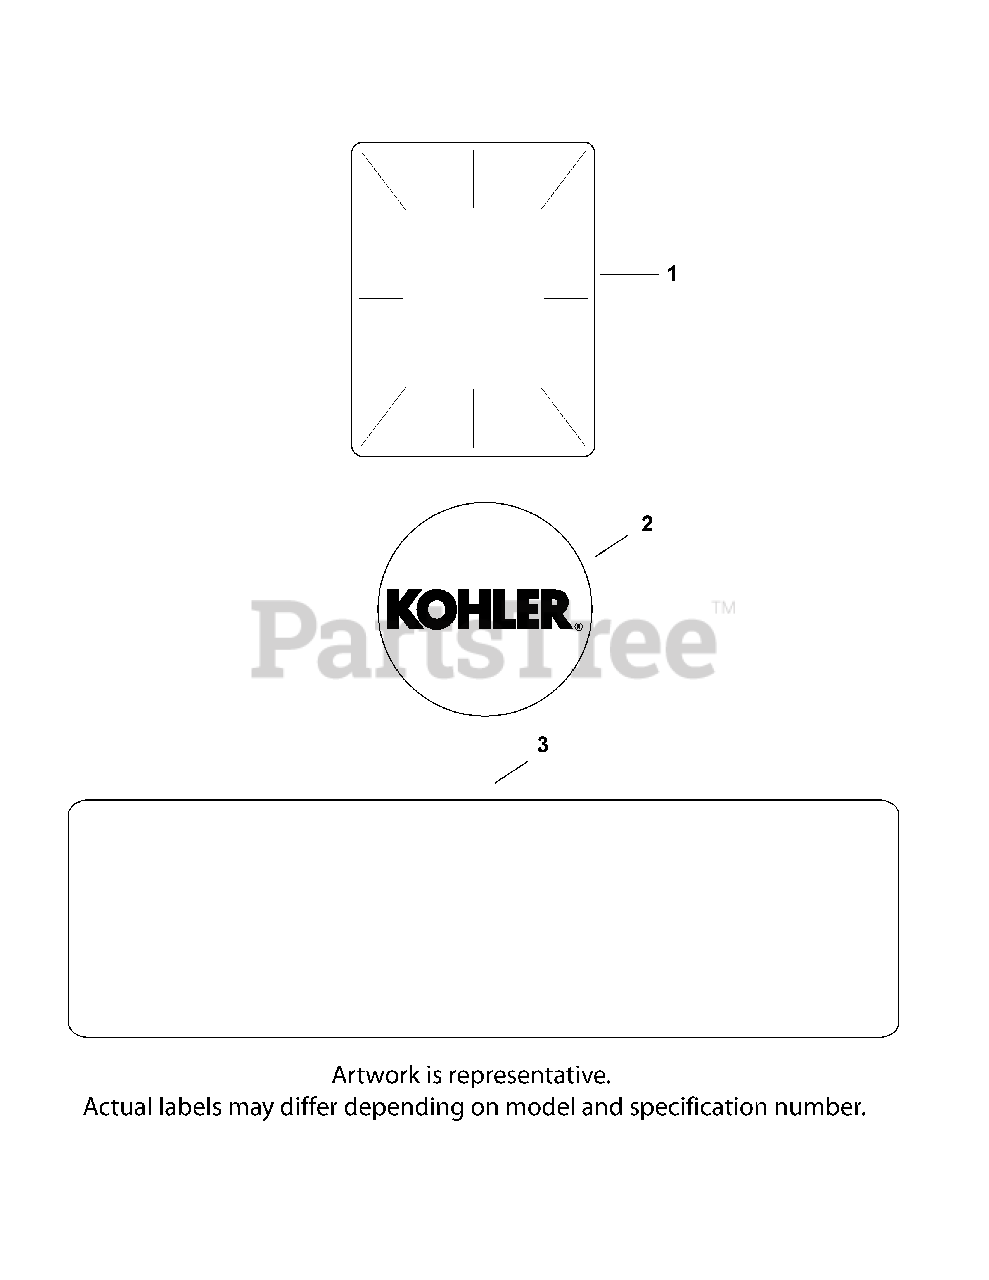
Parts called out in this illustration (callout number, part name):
1	Decal, Clear Laminate
2	Decal, Grass Screen
3	Decal, Command 25 HP
